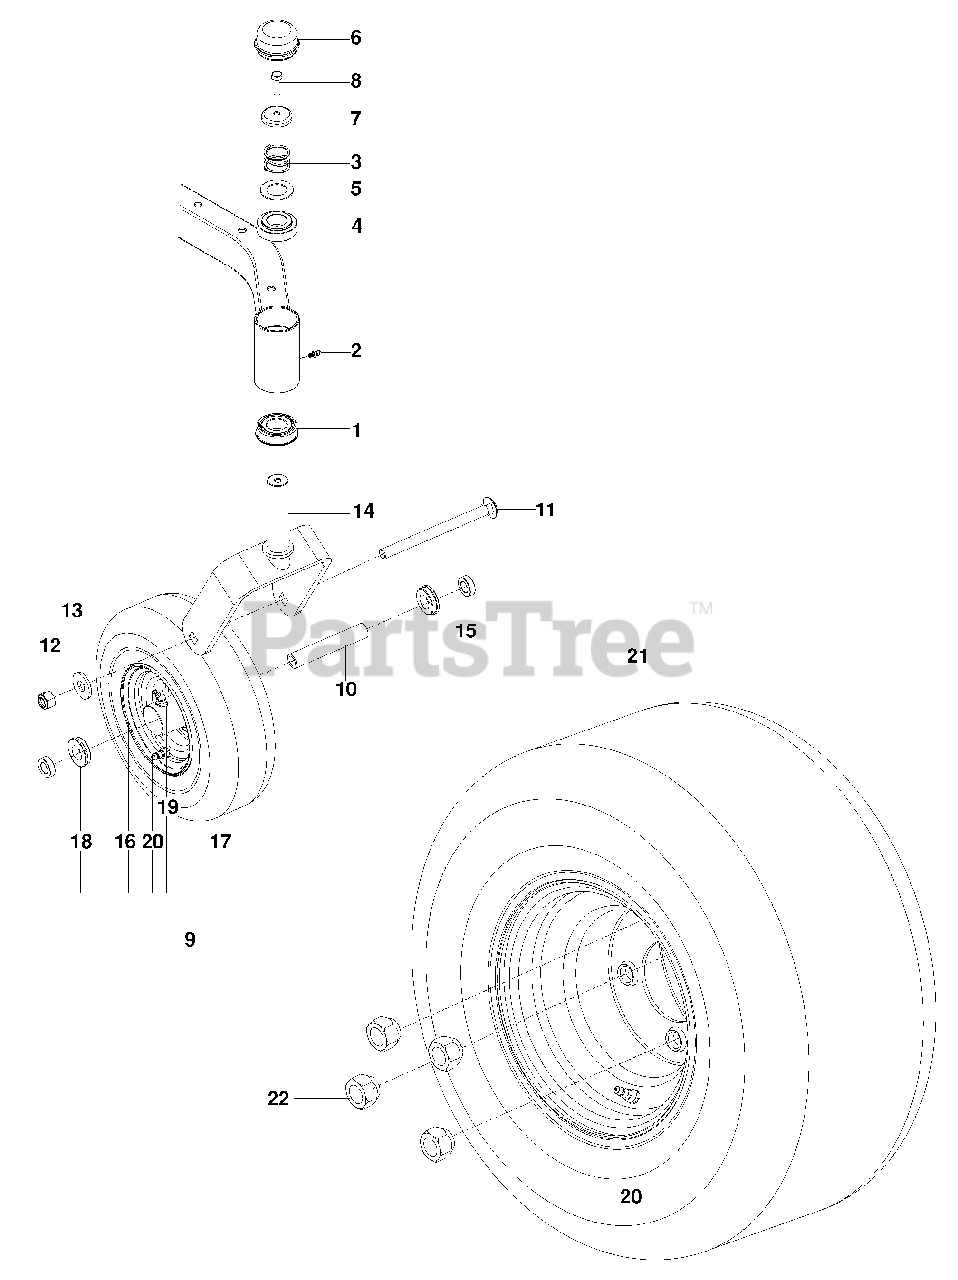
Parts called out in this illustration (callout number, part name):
1	BEARING, FLANGED
2	ZERK 3/16 DRIVE
3	SPRING, CASTER
4	BUSHING, CASTER
5	WASHER
6	GREASE CAP
7	PLUG, CASTER
8	BOLT, HEX 5/16-18 x 1 NYLOC
9	CASTER TIRE ASSY
11	RHSNB 1/2-13 x 6 1/2
12	NUT 1/2-13 HEX NYLOC
13	WASHER 1/2 FLT
14	YOKE ORG
15	SPACER 5/16
17	CASTER TIRE, 410-5 4 PLY
18	BEARING, FLANGED
19	ZERK
20	VALVE STEM
21	WHEEL ASSY, REAR
22	NUT, LUG 1/2
